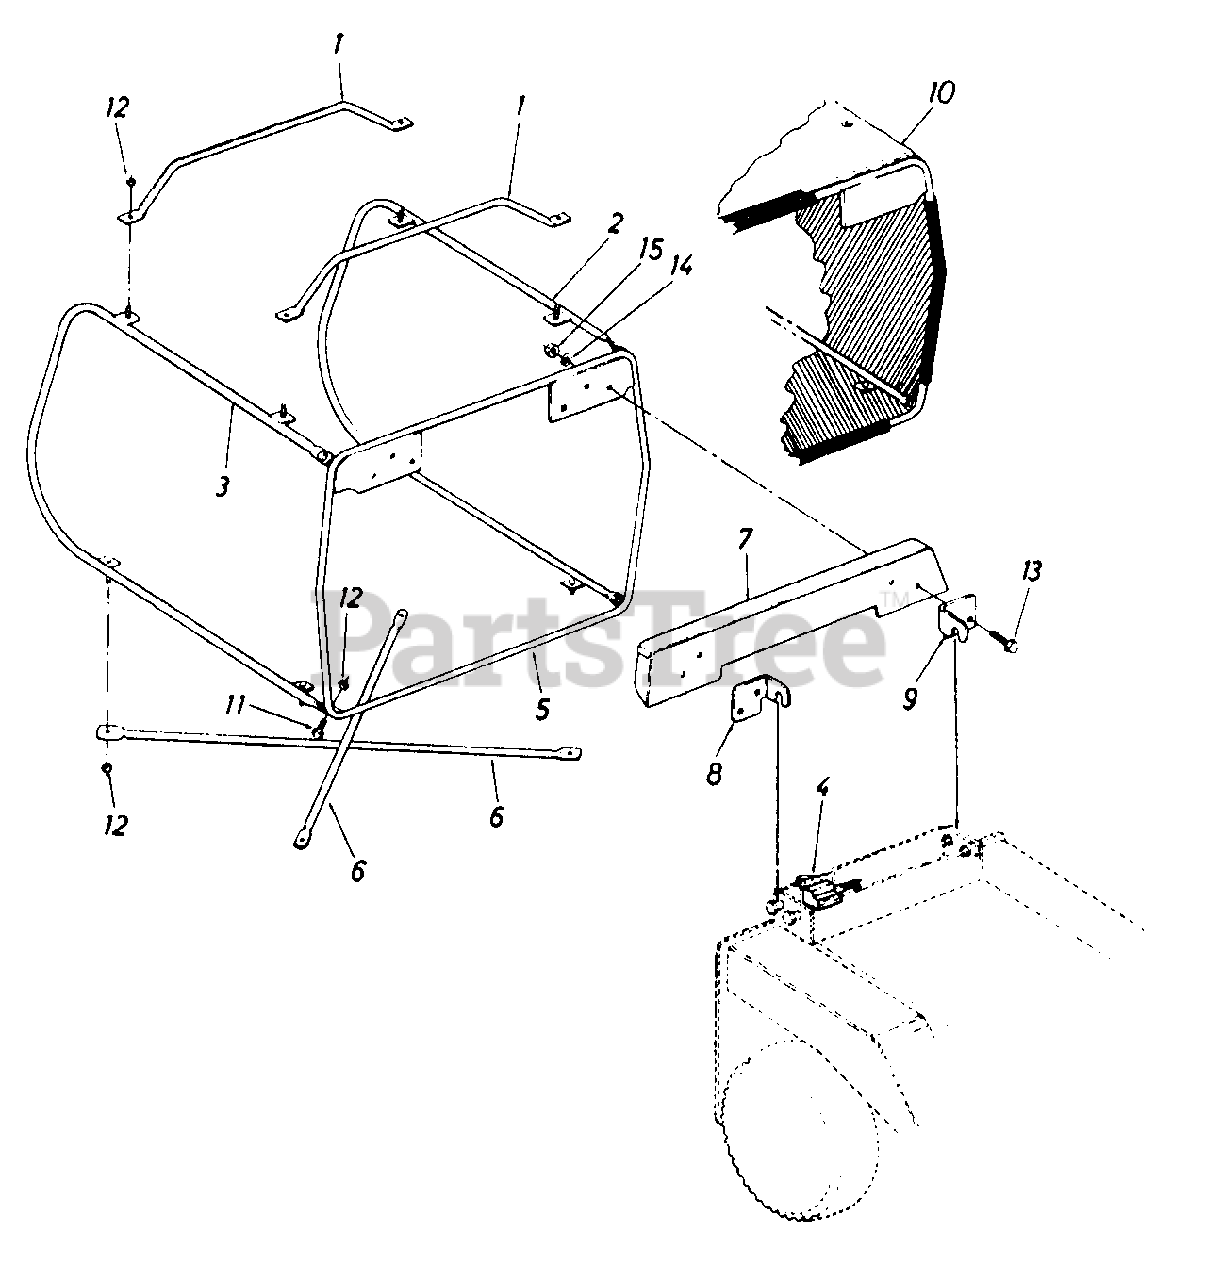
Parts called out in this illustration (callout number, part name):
1	Catcher Handles
2	Catcher Side Frame Ass'y. L.H.
3	Catcher Side Frame Ass'y. R. H.
4	Safety Switch
5	Catcher Frame Ass'y.
6	Bottom Cross Brace
7	Dust Cover
8	Hinge-R.H.
9	Hinge-L.H.
10	Grass Bag
11	Hex Scr. 1/4-20 x .62" Lg.
12	Hex Cent. L-Nut 1/4 20 Thd.
13	Hex Sems Scr. 5116-18 x 1.00" Lg.
14	L-Wash. 5/16" Scr.
15	Hex Nut 5/16-18 Thd
